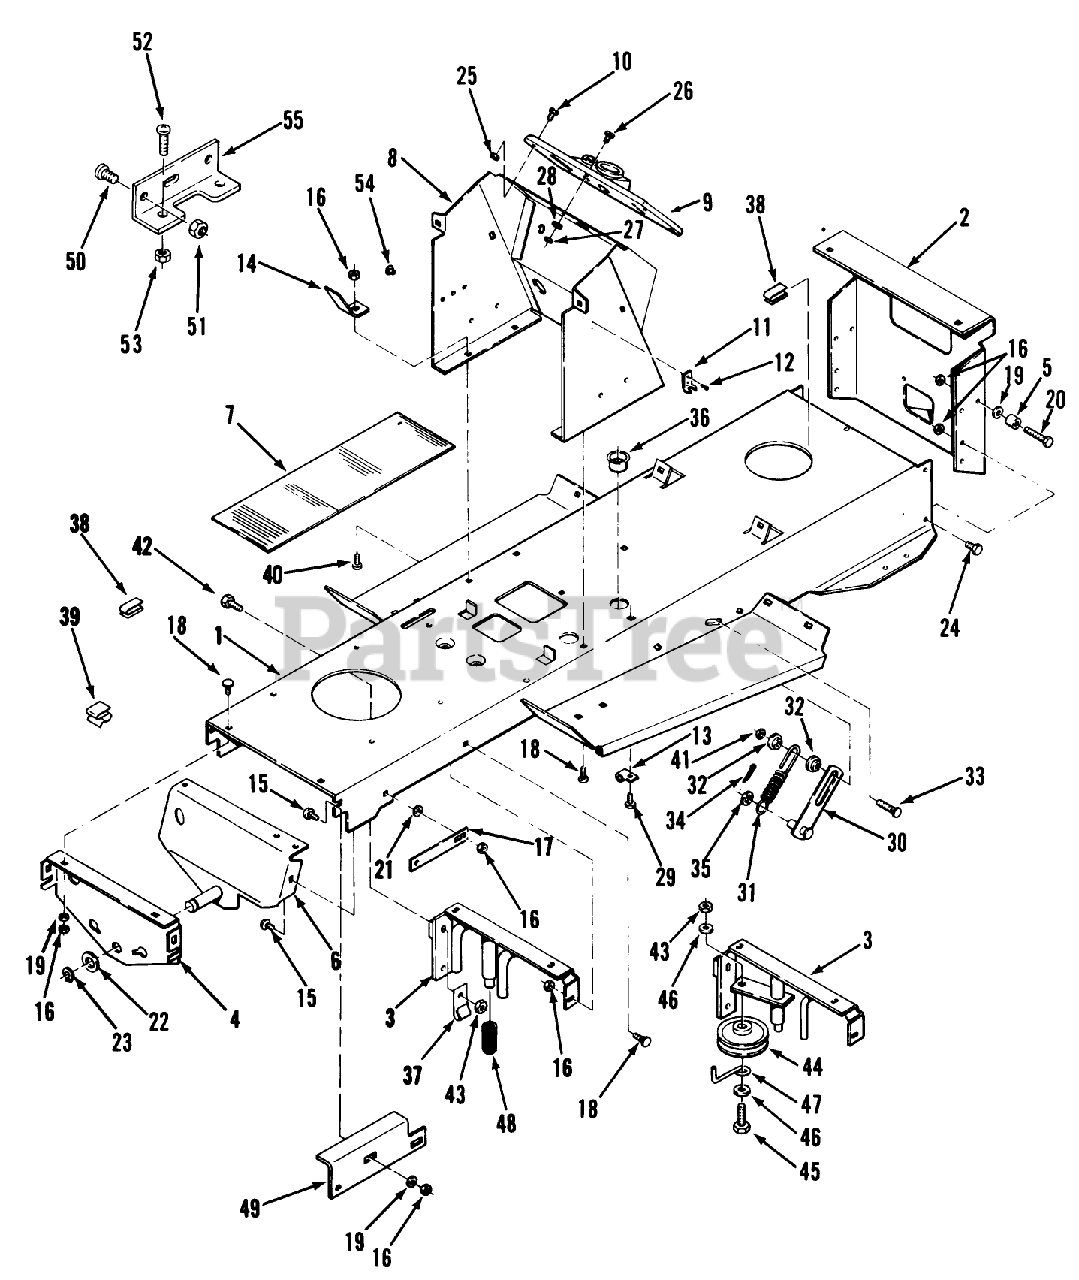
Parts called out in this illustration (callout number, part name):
2	PLATE-DRAWBAR *R
4	PLATE SUPT - AXLE *R
7	PAD-FOOTREST
13	J-CLIP
17	STRAP *R
19	WASHER 5/16 SAE
22	WASHER
31	SPRING
35	WASHER-FLAT
36	BUSHING-NYLON 1.093
37	CLIP
39	CLIP-CABLE
54	PLUG-NYLON .250
